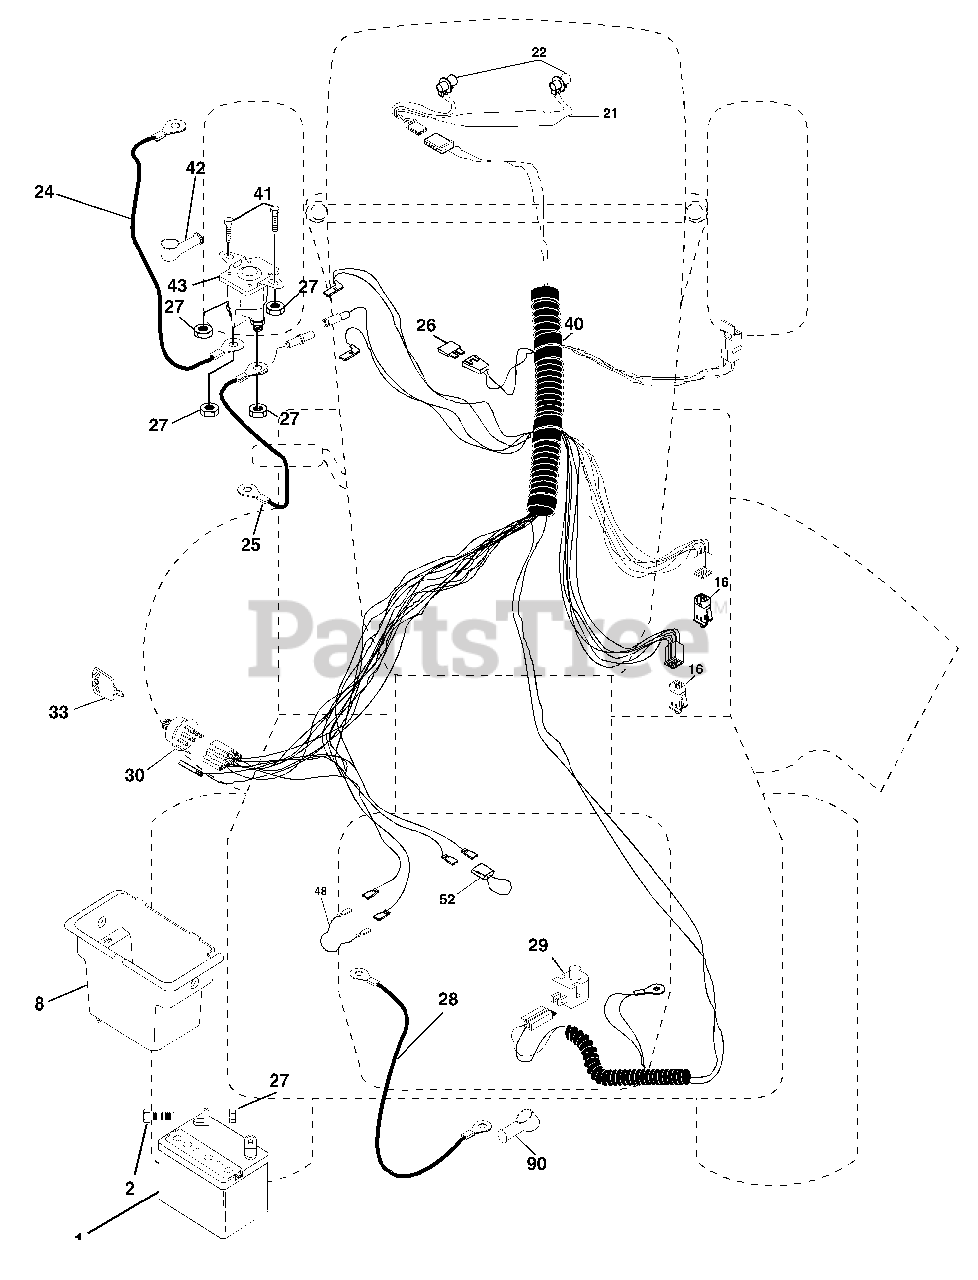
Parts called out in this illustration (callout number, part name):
1	Battery
2	Bolt, Hex Head 1/4-20 unc x 3/4
8	Box Battery Fender
16	Switch, Interlock
21	Harness, Light Socket
22	Bulb, Light
24	Cable, Battery, 6 Gauge, Red, 11"
25	Cable, Battery, 6 Gauge, Red, W/16 Wire
26	Fuse
27	Nut Keps Hex 1/4-20 UNC
28	Cable, Ground, 6 Gauge, Black, 12"
29	Switch, Plunger
30	Switch, Ignition
33	Key, Ignition
40	Harness, Ignition
41	Bolt, Hex Head, Fin. 1/4-20 x 1/2
42	Cover, Terminal, Red
43	Solenoid
48	Adaptor Ammeter Rectangular
52	Protection Wire Loop
89	Cover Terminal Battery
